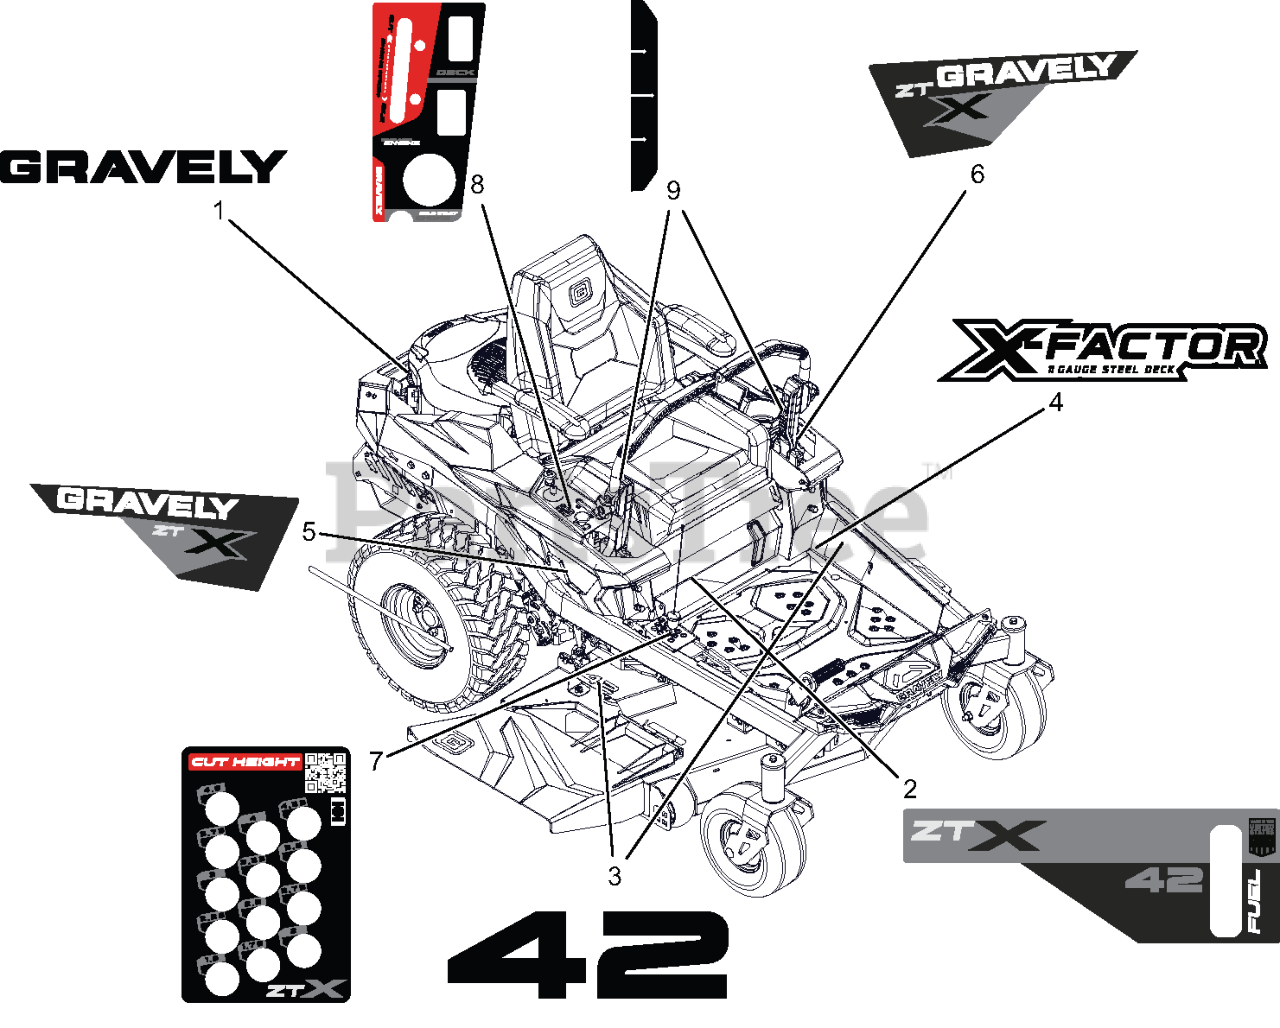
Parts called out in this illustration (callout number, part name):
1	DECAL- GRAVELY
2	DECAL- ZTX 42-KICK PLATE
3	DECAL- DECK 42"
4	DECAL- DECK X-FACTOR
5	DECAL- ZT X FENDER RH
6	DECAL- ZT X FENDER LH
7	DECAL- HEIGHT OF CUT-X
8	DECAL- CONTROL PANEL-GRAVELY
9	DECAL- HIRTH INDICATOR
